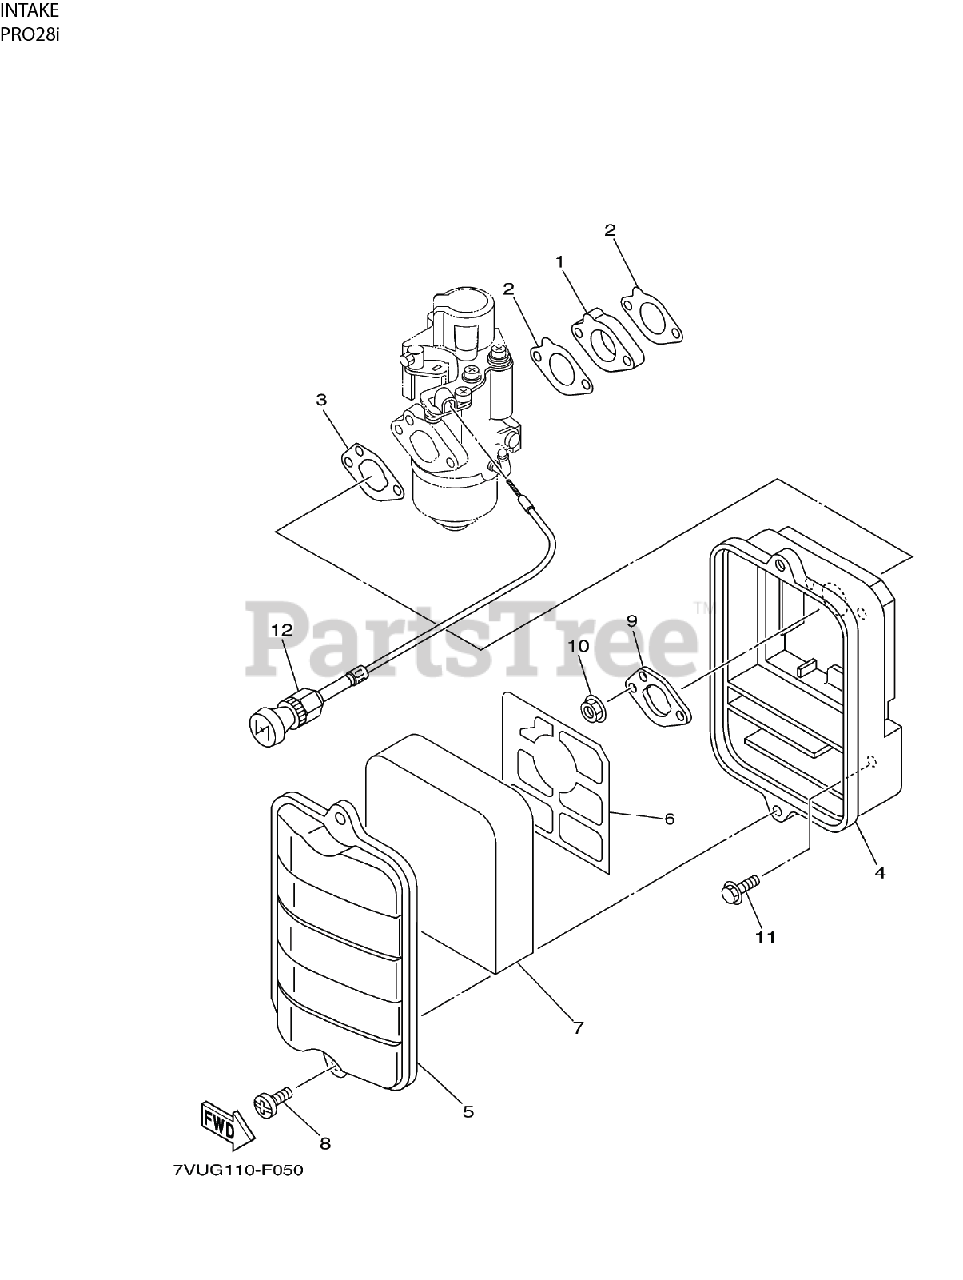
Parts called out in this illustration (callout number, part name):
1	INSULATOR - JOINT CARBURETOR
4	BASE, AIR CLEANER - CASE
5	BASE, AIR CLEANER - CASE
6	PLATE, ELEMENT FITTING
7	ELEMENT, AIR CLEANER
8	SCREW - BOLT
9	SPACER, A/C
10	NUT, FLANGE
11	SCREW - BOLT FLANGE
12	CABLE ASSEMBLY, STARTER
